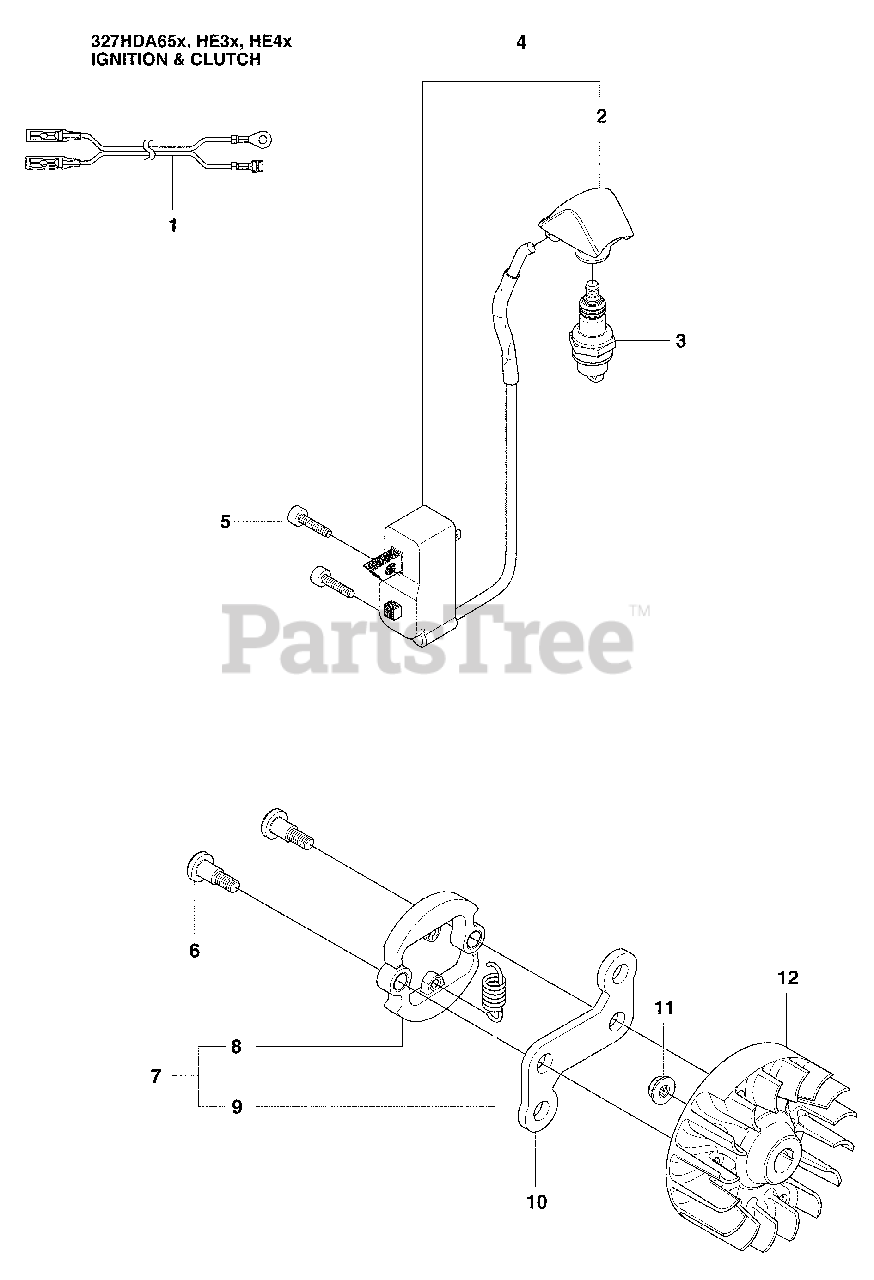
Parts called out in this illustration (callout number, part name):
1	SHORT CIRCUIT CABLE
2	Spark Plug Cap
3	Spark Plug, RCJ6Y
4	Ignition Module, OPS
8	Clutch
9	Clutch Spring
11	CLUTCH YOKE
